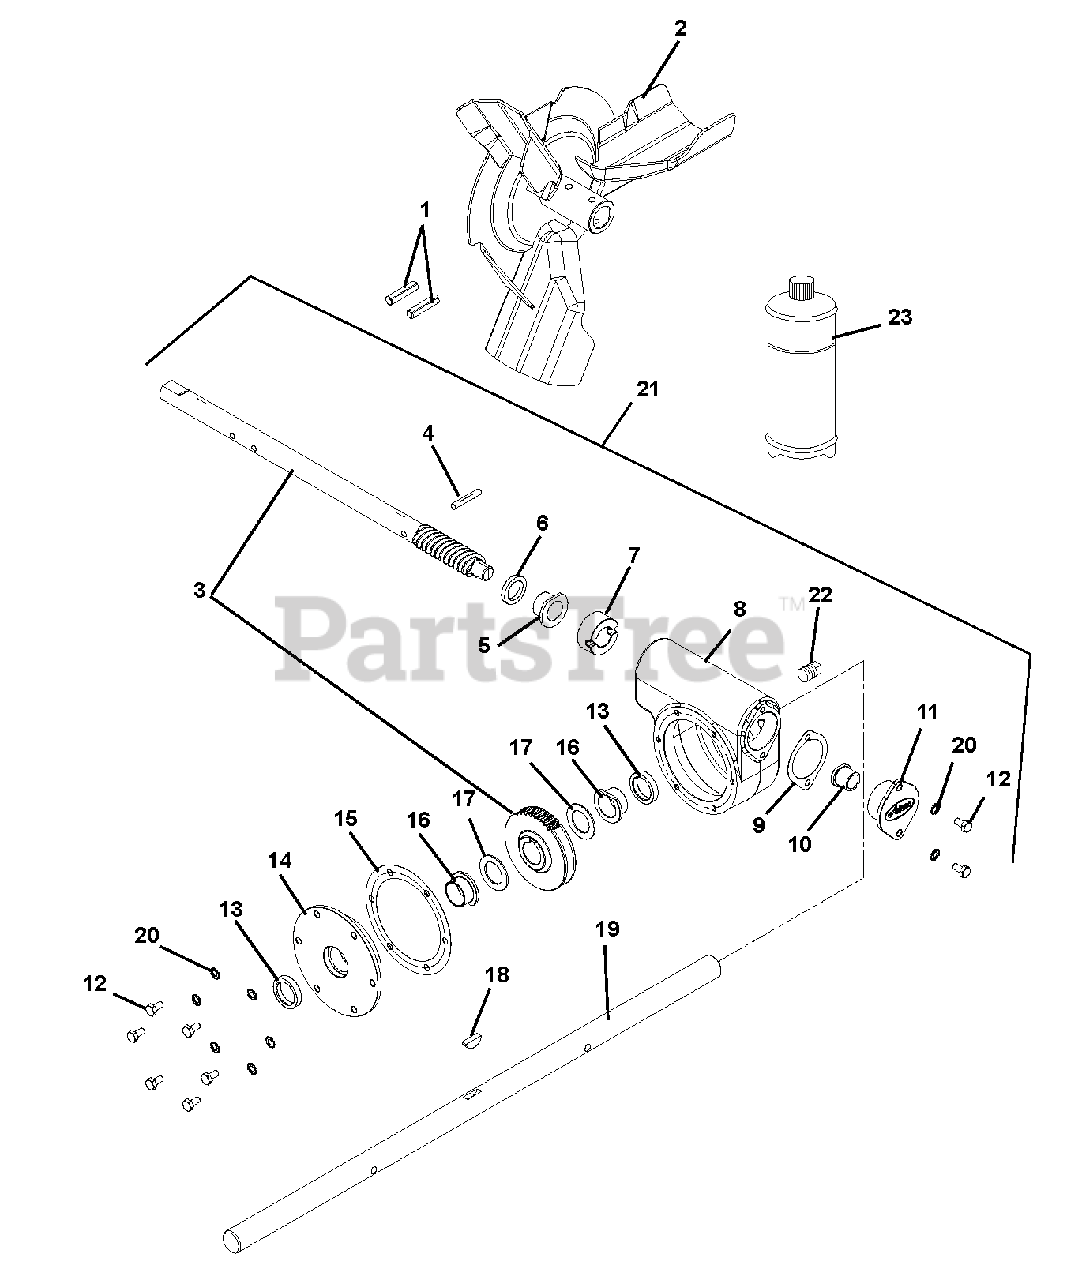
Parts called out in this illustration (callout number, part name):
1	PIN-ROLL .250X1.75
2	IMPELLER, 3 BLADE-14"
3	ASSY, WORM SHAFT & GEAR
4	PIN-GRV .250X1.50 TP E
5	BSHG-FLG .876 X 1.500 X .750
6	SEAL-OIL .875X1.25X.188
7	THRUST COLLAR, .875" ID
8	GEARCASE, CAST IRON-MACHINED
9	GASKET, FRONT - CAST IRON
10	BSHG-FLG .629 X 1.000 X .750
11	COVER, FRONT-CI GEARCASE
12	@BLT-HEX .25-20X.50 GR5 YWZC
13	SEAL-OIL 1.000X1.375X.250
14	COVER, SIDE-CI GEARCASE
15	GASKET, SIDE - CAST IRON
16	BSHG-FLG 1.003X1.5X.625
17	WSHR-HRD-THRS 1.007X1.542X.062
18	KEY-WDRF .25X.875X.375 SAE A
19	SHAFT, RAKE-26"
19	SHAFT, RAKE-28"
19	SHAFT, RAKE-32"
19	SHAFT, RAKE-36"
20	@WSHR-LK-EXT.262X.502X.026YWZC
21	GEAR CASE, CAST IRON-26"
21	GEAR CASE, CAST IRON-28"
21	GEAR CASE, CAST IRON-32"
21	GEAR CASE, CAST IRON-36"
22	PIPE PLUG, 1/4 NPT
23	ARIENS 16 OZ.BOTTLE OF L2 LUBE
